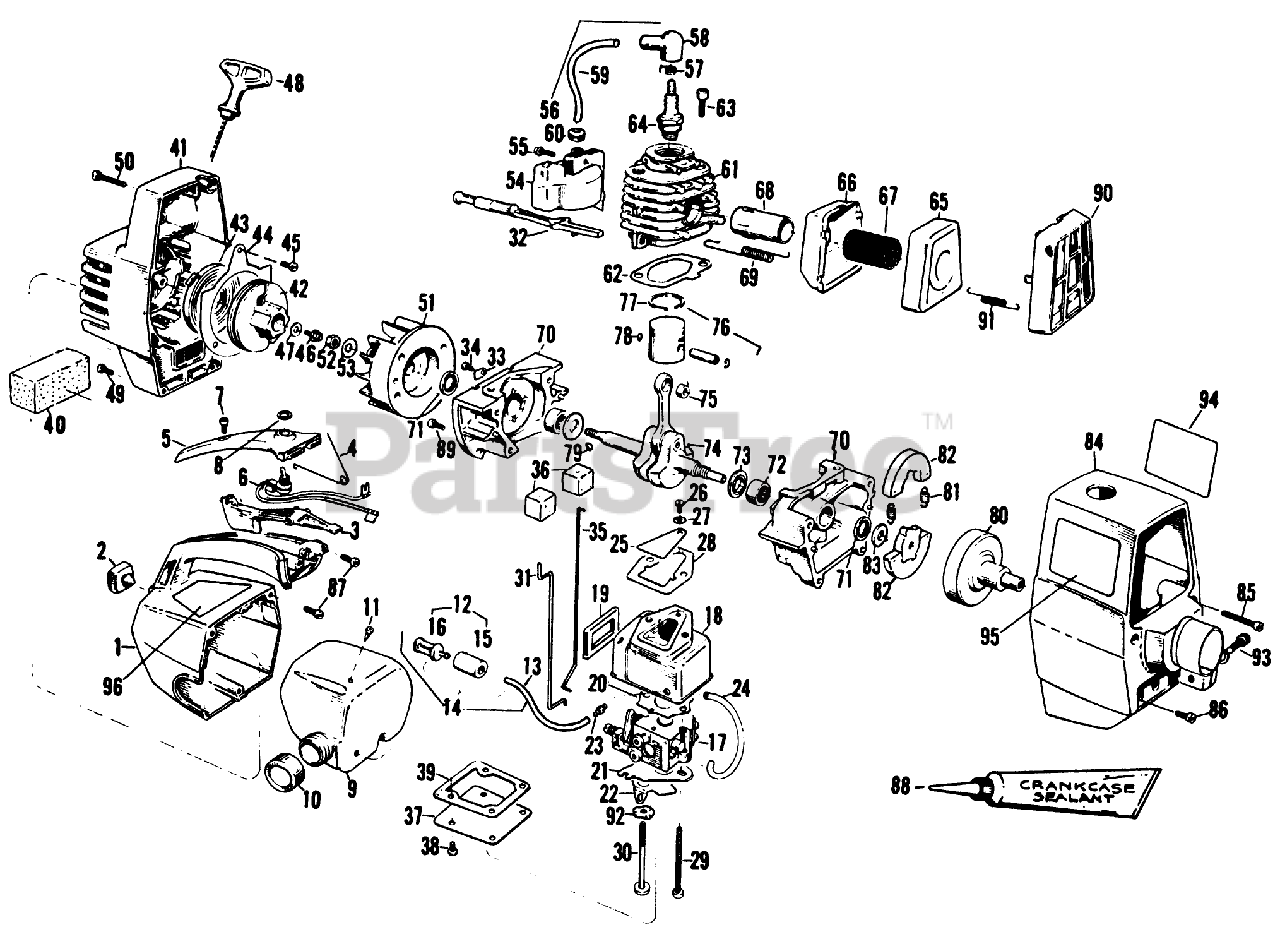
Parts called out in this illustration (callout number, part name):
1	Handle Fuel Tank Housing
2	Bumper-Fuel Tank Housing
3	Trigger-Throttle
4	Trigger Spring
5	Handle Cover
6	Grounding Switch
7	Screw-Handle Cover
8	Nut-Grounding Switch
9	Fuel Tank (Includes 11 13)
10	Fuel Cap
11	Duck Bill Valve
12	Fuel Line Assy
13	Fuel Line
14	Fuel Line Pickup Assy. (Includes 16 17)
15	Fuel Filter
16	Fuel Filter Weight
17	Bushing
18	55013 PLYMOUTH SNWT
19	Seal Carburetor Case
20	Carburetor Gasket
22	Choke Shutter
23	Fuel Line Fitting
24	Fuel Line Carburetor
25	Reed Valve
26	Screw-Reed Valve
27	Washer-Reed Valve Screw
28	Gasket-Carb. Housing to C-case
29	Screw Carburetor
30	Screw-Carburetor Shoulder
31	Choke Wire
32	Choke Knob
33	Clamp-Choke Wire
34	Screw-Choke Rod Clamp
35	Throttle Wire
36	51023/51040 O/P GIL
37	Cover-Carburetor Case
38	Screw-Carburetor Case Cover
39	Gasket-Carburetor Case Cover
40	Air Filter
42	Starter Pulley
43	Starter Recoil Spring
44	Air Baffle
45	Screw Air Baffle
46	Screw-Pulley
47	Washer-Starter Pulley
48	Rope and Handle-Starter
49	Screw-Crankcase
50	Screw-Shroud Top
51	Flywheel Assy
52	Nut-Flywheel
53	Washer-Flywheel
54	Module-Ignition
55	Screw-Ignition Module
56	High Tension Lead Assy
58	Boot-Spark Plug
59	High Tension Lead Wire
60	Grommet-Plug Wire
61	Cylinder
62	Gasket-Cylinder
63	Screw-Cylinder
64	MVP FILTER KIT-GM35XXD (2008- )
65	Cover Muffler
66	Body Muffler
67	Screen-Spark Arresting
68	Diffuser-Muffler
69	Spring-Muffler Attachment
70	Crankcase Assy
71	Seal-Crankshaft
72	Bearing-Crankshaft
73	Washer-Crankshaft Thrust
74	Crankshaft Rod Assy
76	Piston Assy. (Includes 78 79)
77	Piston Ring
78	Retainer-Wrist Pin
79	Key-Flywheel
80	Drum Coupling Bearing Assy
81	Spring-Clutch
82	Clutch Assembly (Includes 82)
83	Washer-Inner
85	Screw-Shroud Top
86	Screw-Crankcase
87	Screw-Fan Housing to handle Fuel Tank
88	MVP FILTER KIT-RM5XXX (2008- )
89	Screw-Crankcase
90	Guard-Muffler
91	Spring-Muffler Guard
92	Washer-Wave
93	Bolt-Pinch Clamp
94	Decal-Shroud (left)
95	Decal-Shroud (right)
96	471A/472A/476B/479B
